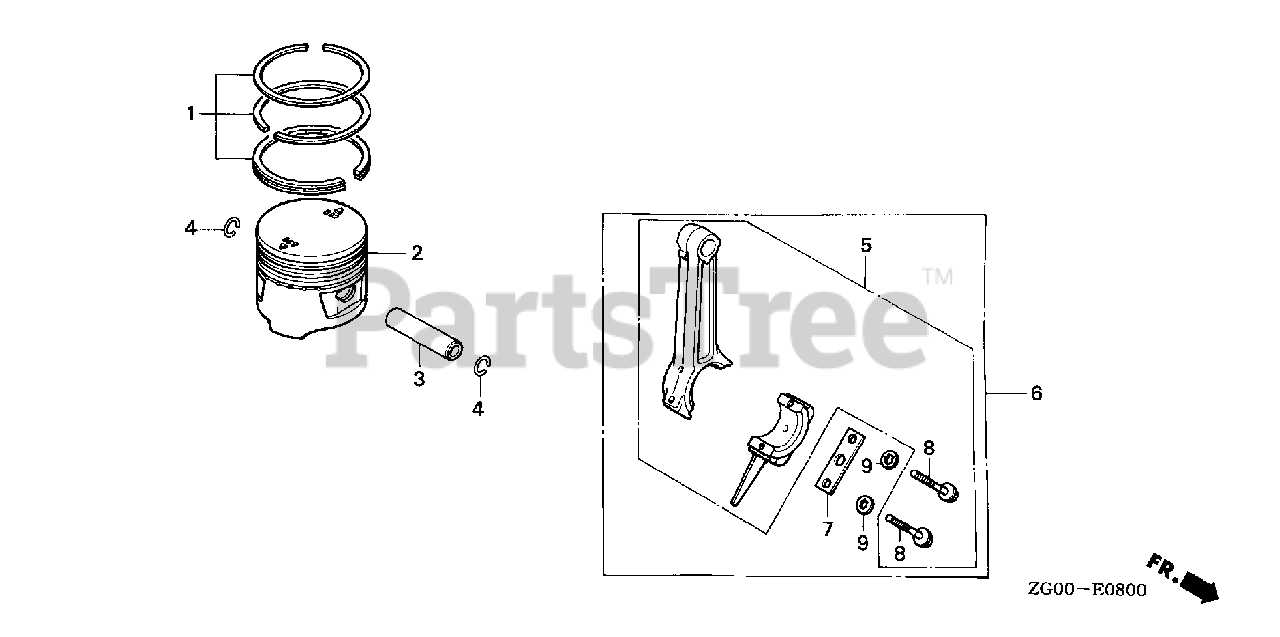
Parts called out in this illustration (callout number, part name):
1	RING SET, PISTON (STD)
1	RING SET, PISTON (OS 0.25)
1	RING SET, PISTON (OS 0.50)
1	RING SET, PISTON (0.75)
2	PISTON (STD)
2	PISTON (OS 0.25)
2	PISTON (OS 0.50)
2	PISTON (0.75)
3	PIN, PISTON
4	CLIP, PISTON PIN (10MM)
5	ROD ASSY., CONNECTING (STD)
5	ROD ASSY., CONNECTING (US)
8	BOLT, CONNECTING ROD
